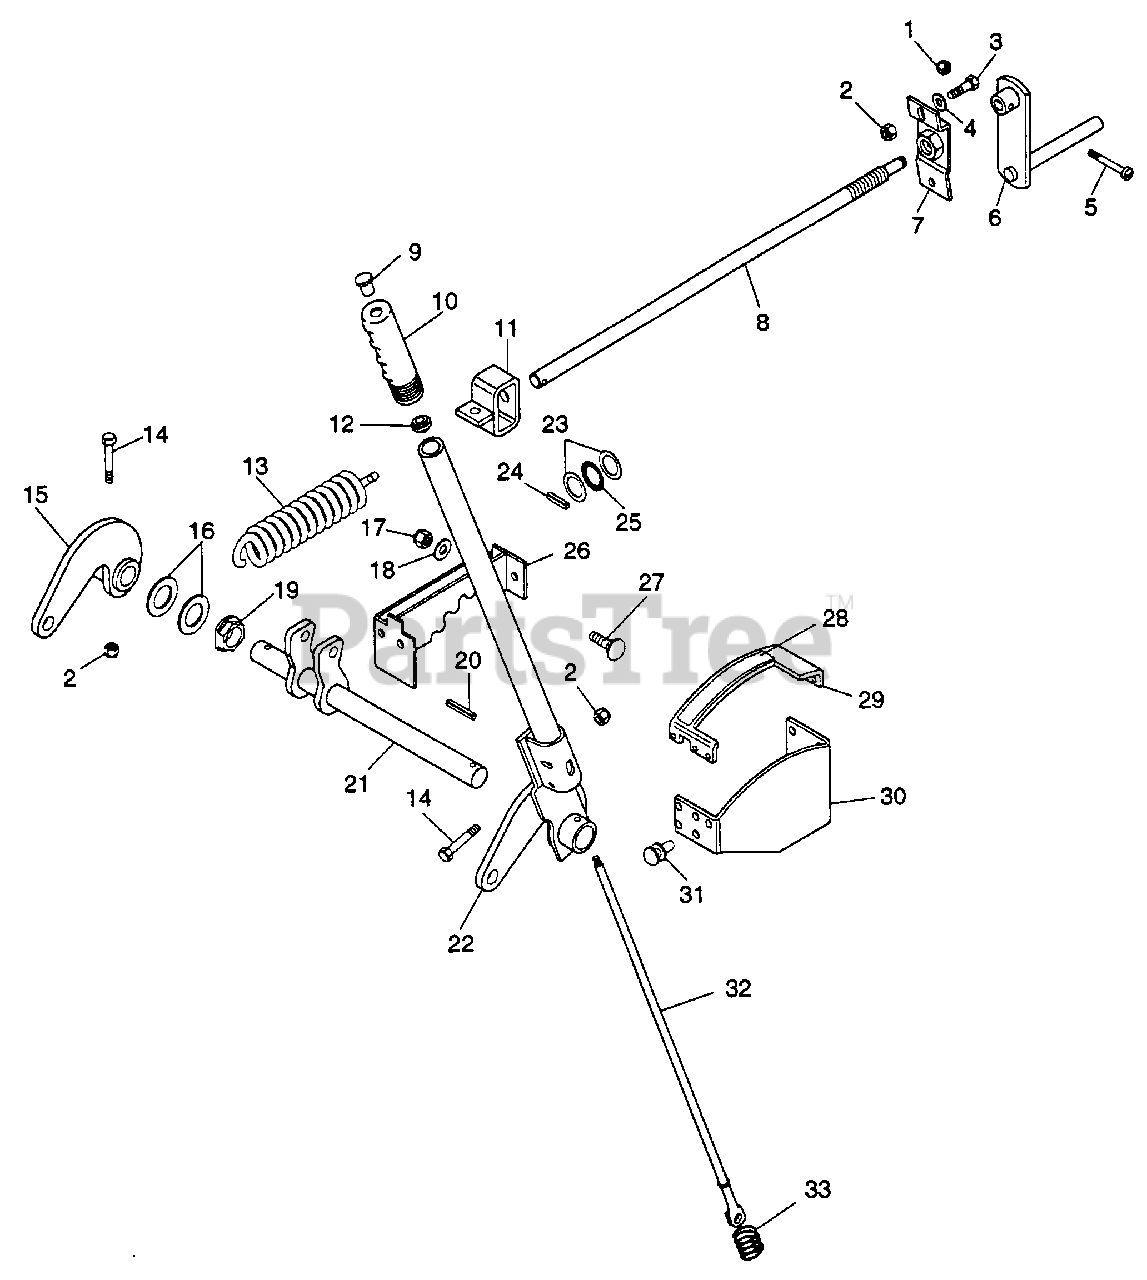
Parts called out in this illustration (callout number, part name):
1	Nut-Lk 10-24 Ny Pl
2	Nut-Lk-Nyl .250-20 Pl
3	Blt-Hex .25-20 x 1.00 Pl Gr 5
4	Wshr-Fl-Stl .281 x .625 x .065
5	Scr-Mch 10-24 x 1.25 Phcr
6	Handle
7	Crank
8	Jackscrew
9	Knob
10	Grip, Flex
11	Weldment Tube
12	Guide, Push Rod
13	Sg-Lift .244 x 1.75 x 7.6 Rate 70
14	Blt-Hex .25-20 x 1.75 Gr 2
15	Weldment, Lift Hub
16	Wshr-Thrst 1.55 x 1.002 x .093
17	Nut-Lk-Nyl .312-18 Pl
18	Wshr-Fl-Stl .344 x .688 x .065
19	Bshg-Flg 1.000 x 1.25 x .49 x 1.56 Hx
20	Pin-Sg .250 x 1.875
21	Lift Pivot
22	Lift Lever
23	Wshr-Thrst .507 x .917 x .031
24	Pin, Spring .250 x 1.000
25	Brg-Thrst .502
26	Lift Quadrant
27	Blt-Carriage .31-18 x .75
28	Decal Lift
29	Cover, Top
30	Cover, Lift
31	Fastener
32	Rod, Push
33	Sg-Comp .055 x .845 x .750 Wld 10
